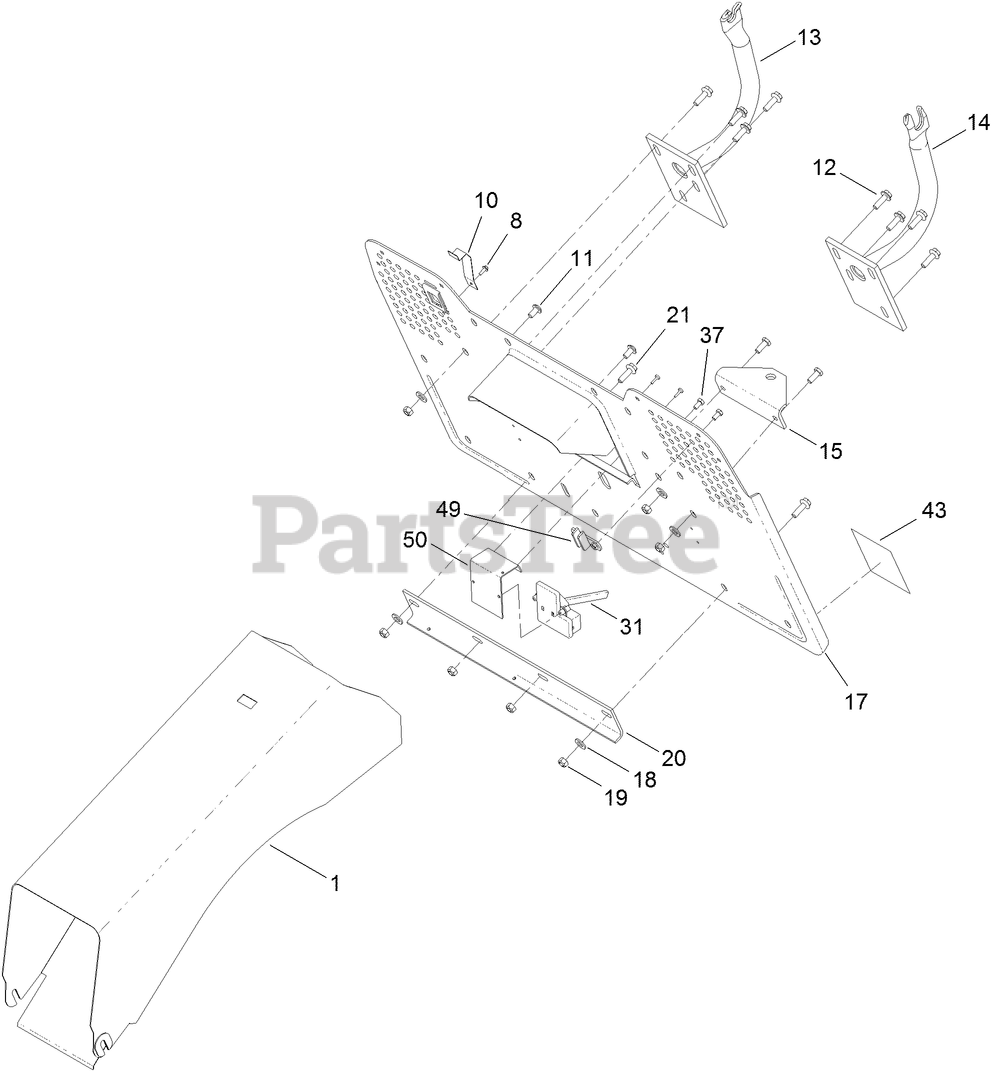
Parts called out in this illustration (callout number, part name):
1	TUNNEL
10	BRACKET-BAG PRESENT SWITCH
11	BOLT-CARRIAGE
13	SUPPORT-COLLECTOR, RIGHT
14	SUPPORT-COLLECTOR, LEFT
15	HITCH-TOW
17	PLATE-COLLECTOR
18	WASHER-FLAT
19	NUT-LOCK, NI
20	BRACKET-HITCH, SUPPORT
21	SCREW-HEX
31	SWITCH-OMRON
37	SCREW-HH
43	DECAL-BYPASS, HYDRO
49	BRACKET-SUPPORT, FUEL TANK
50	BRACKET-SWITCH
